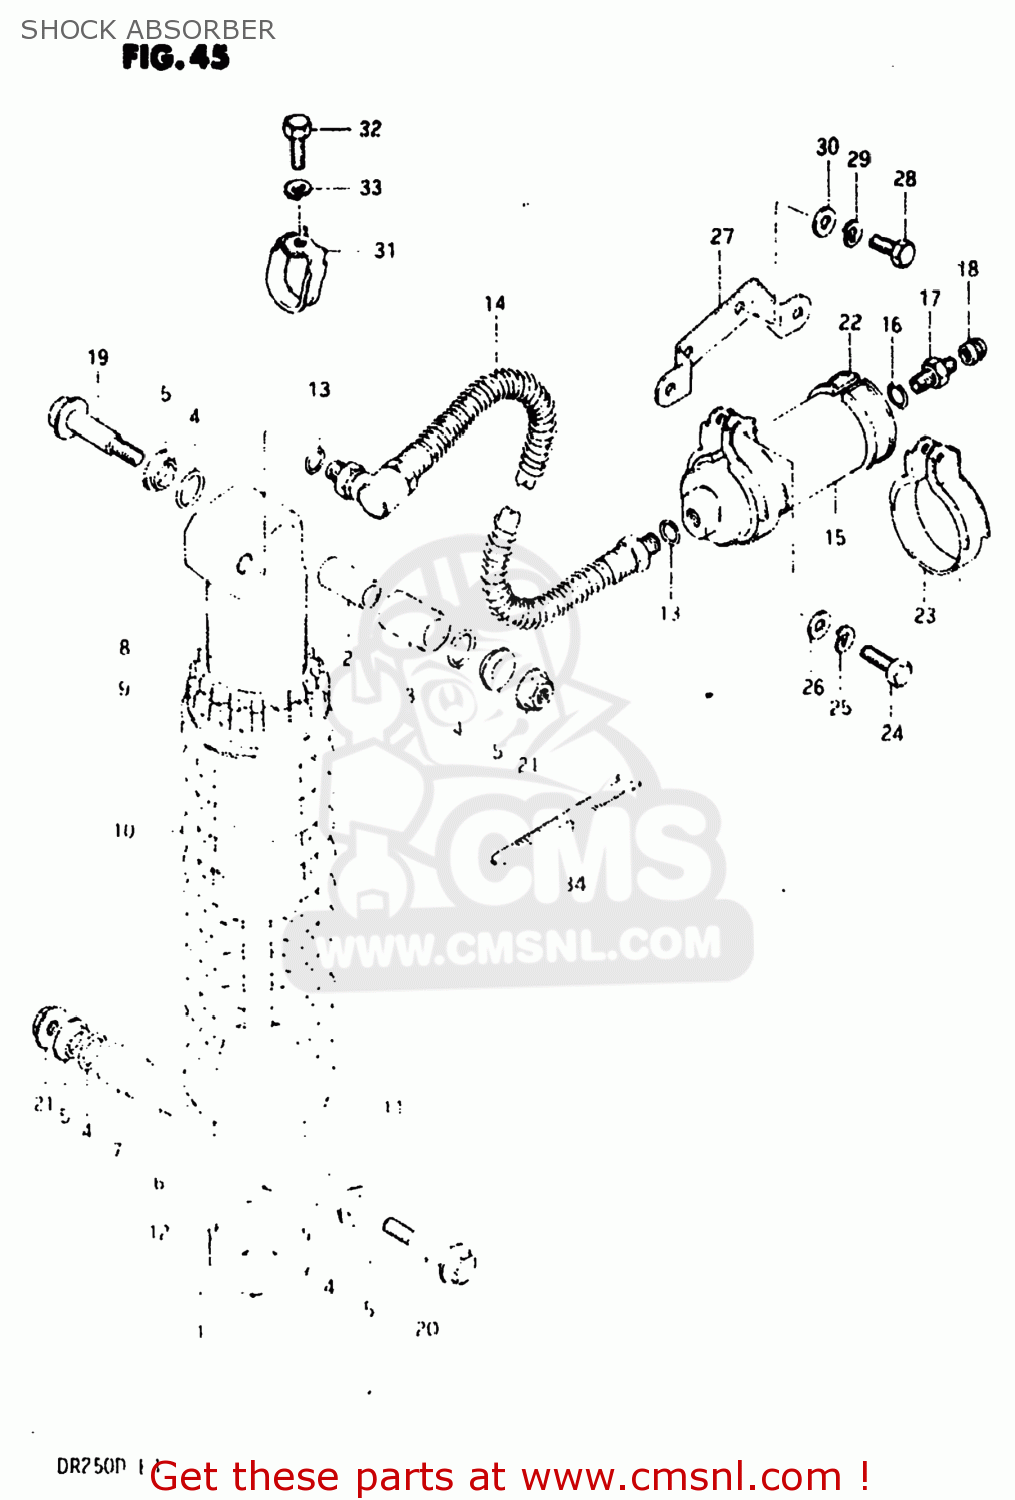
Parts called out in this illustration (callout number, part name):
1	ABSORBER ASSEMBLY,REAR SHOCK
2	BUSH
3	BUSHING,REAR SHOCK,UPPER
4	O-RING,FORK INNER TUBE
5	COLLAR
6	BUSHING,REAR SHOCK ABSORBER
7	BUSHING,REAR SHOCK,LOWER
8	NUT
9	GUIDE,SPRING
10	SPRING
11	GUIDE,SPRING
12	CLIP
13	O-RING,RESERVE TANK
14	HOSE,REAR SHOCK ABSORBER
15	RESERVE TANK,REAR SHOCK
16	O-RING
17	VALVE ASSEMBLY,REAR CUSHION
18	CAP,FRONT FORK AIR VALVE
19	BOLT(10X60)
20	BOLT(10X52)
21	NUT
22	CUSHION,REAR SHOCK ABSORBER TANK
23	BRACKET,RESERVOIR TANK
24	BOLT, UPPER
25	LOCK WASHER
26	WASHER
27	PLATE,BRACKET
28	BOLT
29	LOCK WASHER
30	WASHER
31	GUIDE,HOSE
32	SCREW 6X12
33	LOCK WASHER
34	CLAMP
